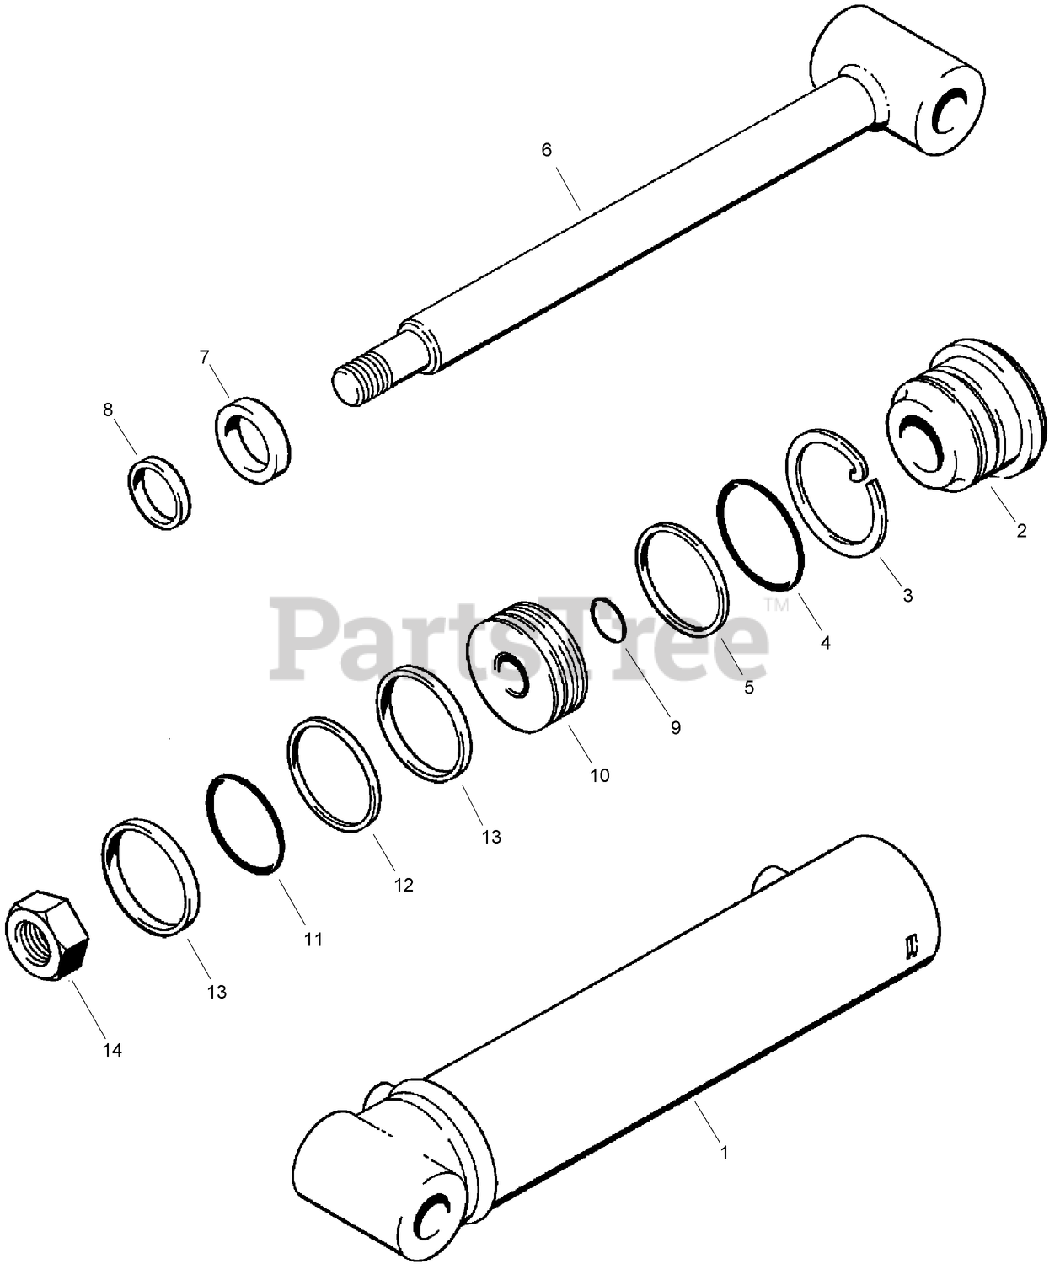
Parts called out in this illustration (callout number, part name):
1	CASE ASM
3	WIRE-locking, gland
4	O-RING-gland
5	RING-backup, gland O-ring
6	ROD-piston
7	WIPER-piston rod
8	SEAL-U-cup, piston rod
9	O-RING-piston rod, nut end
11	O-RING-piston
12	RING-backup, piston O-ring
13	RING-wear, piston
14	NUT-LOCK
